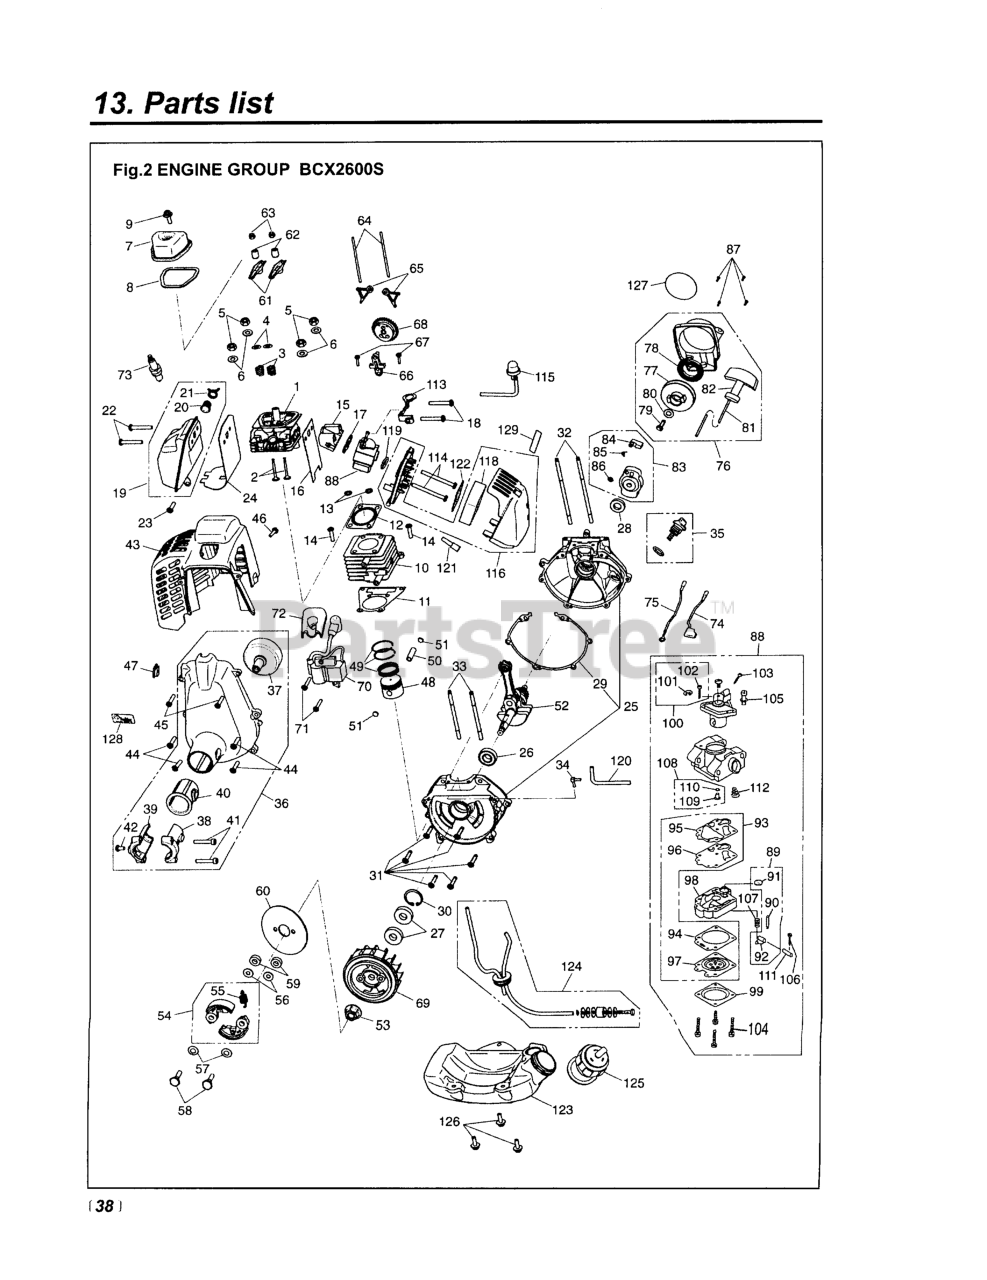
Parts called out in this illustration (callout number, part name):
1	182306 (REPLACES 2062-95110)
2	VALVE (RPLS 2062-11510)
3	SPRING, VALVE (RPLS 2062-11520
4	RETAINER (RPLS 2063-11530)
5	NUT (RPLS 2062-11310)
6	WASHER (RPLS 2062-11320)
7	COVER, VALVE (RPLS 2062-11410)
8	GASKET (RPLS 2062-11420)
9	SCREW (RPLS 2062-11430)
10	CYLINDER (RPLS 2062-12110)
11	GASKET, BASE (RPLS 2062-12210)
12	GASKET, HEAD (RPLS 2062-12220)
13	O-RING (RPLS 2062-12230)
14	SCREW (RPLS 2062-12240)
15	INSULATOR (RPLS 2062-13160)
16	GASKET (RPLS 2062-13120)
17	GASKET, CARB (RPLS 2062-13130)
18	SCREW (RPLS 2062-15220)
19	MUFFLER ASSY (RPLS 2062-15100)
20	ARRESTER (RPLS 2062-15140)
22	SCREW (RPLS 2062-15220)
23	SCREW (RPLS 2062-15230)
24	GASKET (RPLS 2062-15210)
25	CRANKCASE (RPLS 2062-95120)
26	BEARING (RPLS 2062-21420)
27	SEAL (RPLS 2062-21220)
28	SEAL (RPLS 2062-21210)
29	GASKET, BASE (RPLS 2062-21140)
30	RING, SNAP (RPLS 2062-21520)
31	SCREW (RPLS 5850-13210)
32	STUD (RPLS 2062-21160)
33	STUD (RPLS 2062-21170)
34	ELBOW (RPLS 2062-21620)
35	PLUG & 0-RING(RPLS 2062-95130)
36	HOUSING-A (RPLS 2063-31100)
37	DRUM, CLUTCH (USE 182298)
38	BRACKET (A) (RPLS -31210)
39	BRACKET (B) (REPLACES -31220)
40	CUSHION
42	BOLT (USE 3310-31720)
43	COVER, ENGINE (RPLS 2063-32110
44	SCREW (RPLS 2062-12240)
45	SCREW (RPLS 5850-32170)
46	SCREW (RPLS 2062-32140)
47	GROMMET (RPLS 1852-72121)
48	PISTON (RPLS 2063-41110)
49	RING (RPLS 2063-95140)
50	PIN, PISTON (RPLS 2062-41310)
51	BUTTON (RPLS 2062-41320)
52	SHAFT & GEAR (RPLS 2063-45000)
53	NUT (REPLACES 1650-43230)
54	SHOE, CLUTCH (RPLS.2063-51100)
55	SPRING
56	WASHER (REPLACES 1140-51230)
57	WASHER, SPRING (RPL 1970-51241
58	SCREW (REPLACES 2063-51250)
59	SPACER (RPLS 2063-51260)
60	DISK (RPLS 2063-51310)
61	ARM, ROCKER (RPLS 2062-61160)
62	PIVOT (RPLS 2062-61170)
64	ROD, PUSH (RPLS 2062-61210)
65	FOLLOWER, CAM (RPLS 2062-61310
66	BRACKET, CAM (RPLS 2062-61400)
67	SCREW (RPLS 2062-61610)
68	GEAR,CAM (RPLS 2062-61500)
69	ROTOR (RPLS 2063-71110)
70	COIL (RPLS 2062-71200)
71	SCREW, COIL (RPLS 2062-71310)
72	CAP, COVER (RPLS 2063-72140)
74	CORD (A)
75	CORD (B)
76	RECOIL (RPLS 2062-95150)
77	REEL (RPLS 5850-75120)
78	SPRING (RPLS 5850-75130)
79	SCREW (RPLS 5850-75140)
80	WASHER (REPLACES 1400-86280)
81	ROPE (RPLS 5850-75150)
82	KNOB (RPLS 5850-75160)
83	PULLEY ASSY
84	RATCHET (RPLS 5850-75220)
85	SPRING (RPLS 5850-75230)
86	RING, SNAP (RPLS 0308-00040)
87	SCREW (RPLS 2062-75310)
88	CARBURETOR (RPLS 2062-81000)
90	VALVE, INLET
91	SCREEN
92	LEVER
93	KIT, GASKET (D11-WYL)
94	GASKET
95	GASKET, PUMP
96	DIAPHRAGM, PUMP
97	DIAPHRAGM
98	BODY ASSEMBLY, PUMP
99	COVER, DIAPHRAGM
100	SWIVEL - A
101	RING, SPRING RETAINING
102	SWIVEL
103	SCREW, IDLE AD
106	SCREW, METERING LEVER PIN
107	SPRING, METERING LEVER
108	KIT, MAIN JET
109	JET
110	O-RING
111	PIN, METERING LEVER
112	SPRING, DIAPHRAGM PUMP
113	BRACKET (RPLS 2062-83110)
114	SCREW (RPLS 2062-83120)
116	CLEANER (RPLS 2062-82000)
118	ELEMENT (RPLS 2062-82150)
119	RING (RPLS 5850-83110)
120	HOSE (RPLS 2062-82310)
121	BREATHER ASSY (RPLS 2062-82400
122	SCREEN (SUB 2062-82160)
123	TANK (RPLS 2063-85000/85110)
124	FUEL LINE ASSY.
125	CAP (RPLS 2062-85200)
126	SCREW (RPLS 2062-85510)
127	LABEL, RECOIL (RPL 2063-91120)
128	LABEL, HOUSING (RPL 2063-91160
129	LABEL, CLEANER (RPL 2062-91180
